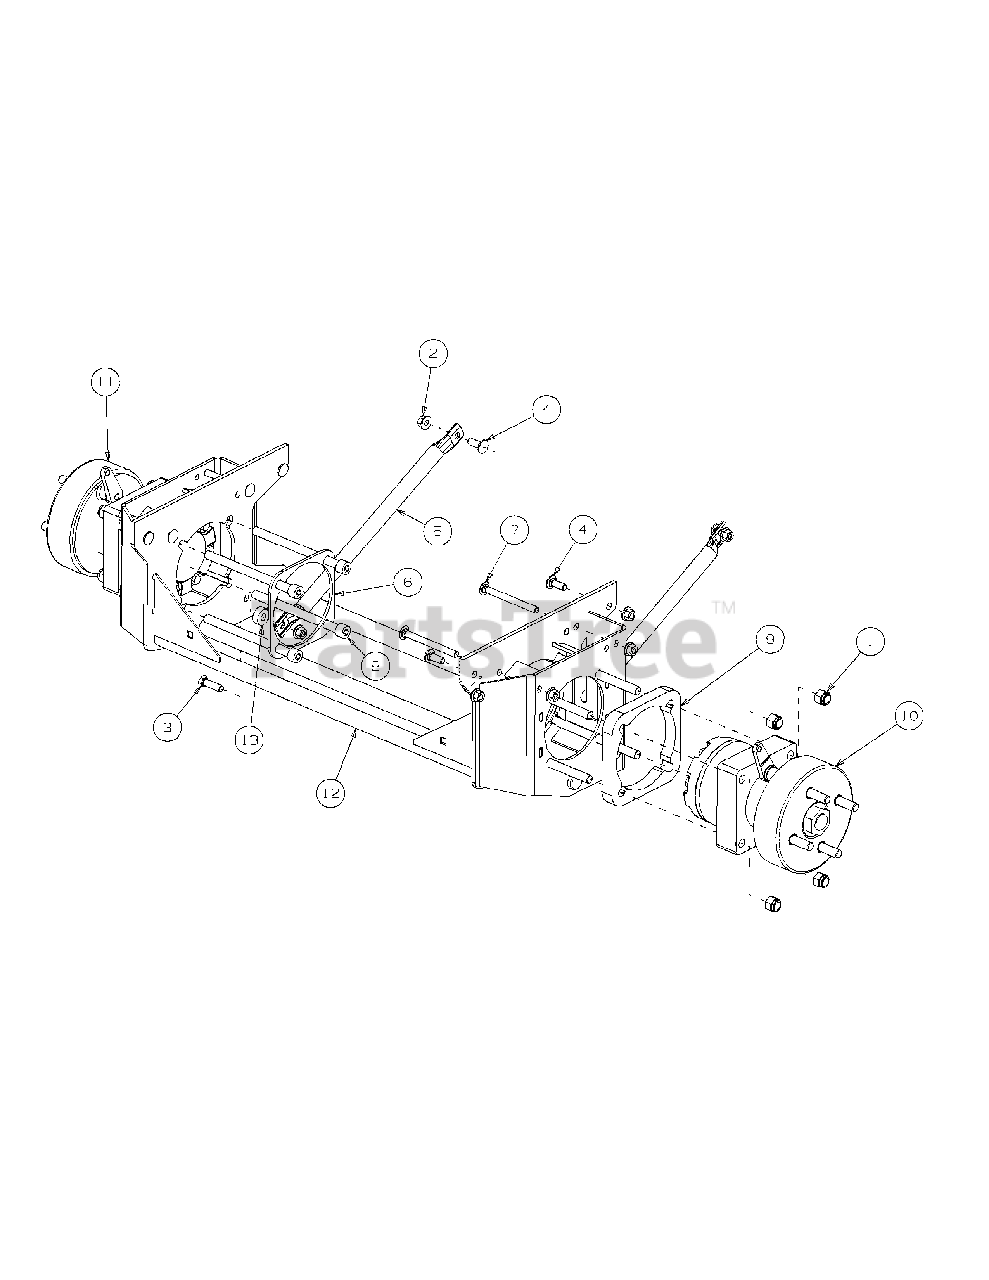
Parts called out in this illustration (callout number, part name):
1	Lock Nut, Nylon Insert, 1/2-13
2	Flange Lock Hex Nut, 3/8-16
3	Hex Cap Screw, 2/8 -16 x 1.25
4	Carriage Bolt, 3/8-16 x 1
7	Carriage Bolt, 3/8-16 x 4"
8	Socket Head Capscrew, 1/2-13 x 6-1/2
9	Hydro Motor Spacer
10	Hyd. Motor, White Left Hand
11	Hyd. Motor, White Right Hand
12	Hydro Motor Frame Assembly
13	Spacer .406 ID x 1.0 OD
